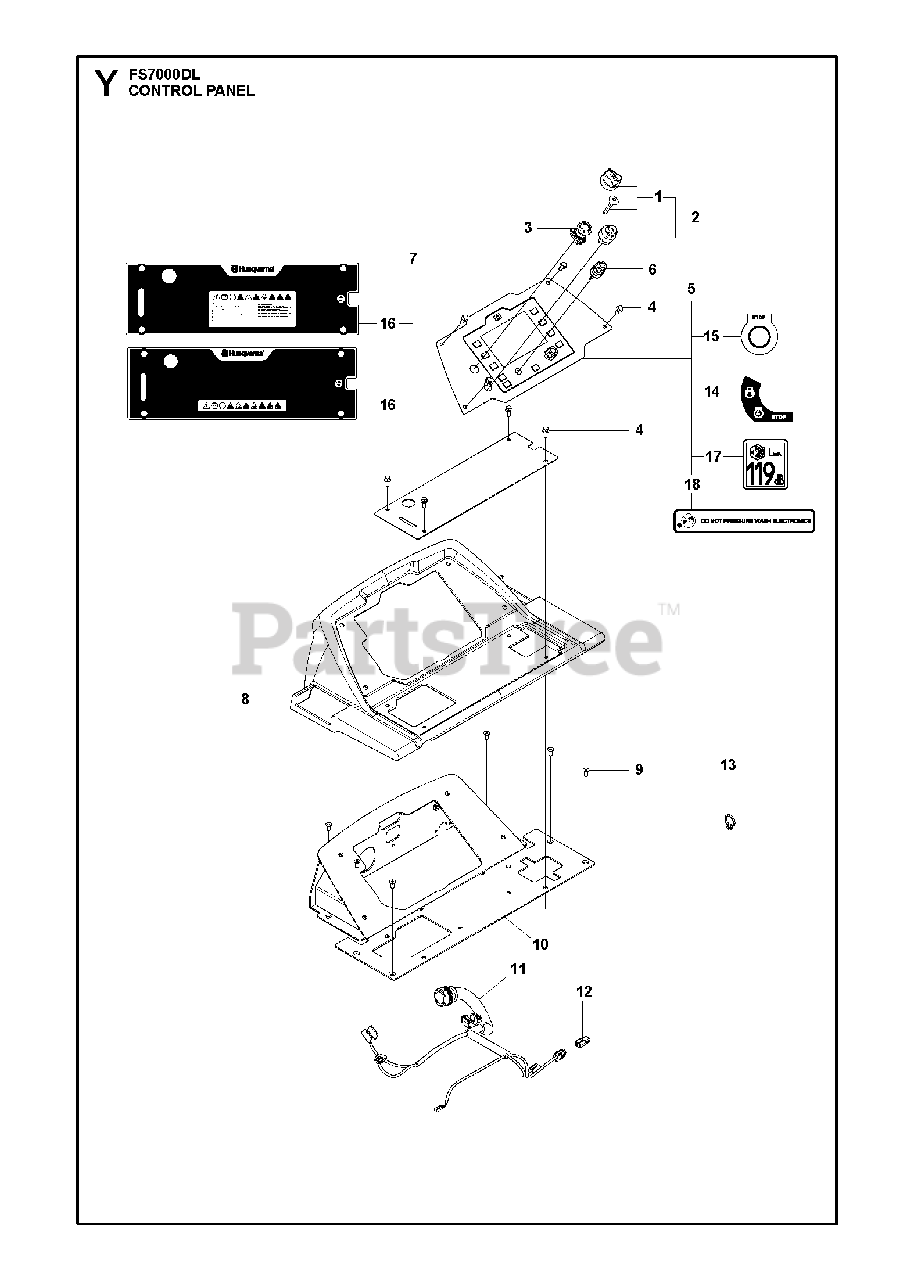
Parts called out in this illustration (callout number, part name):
2	IGNITION SWITCH1+2 together
5	CONTROL PANELIncl. Decals
7	PANELIncl. Decals, US only
7	PANELIncl. Decals, EU only
